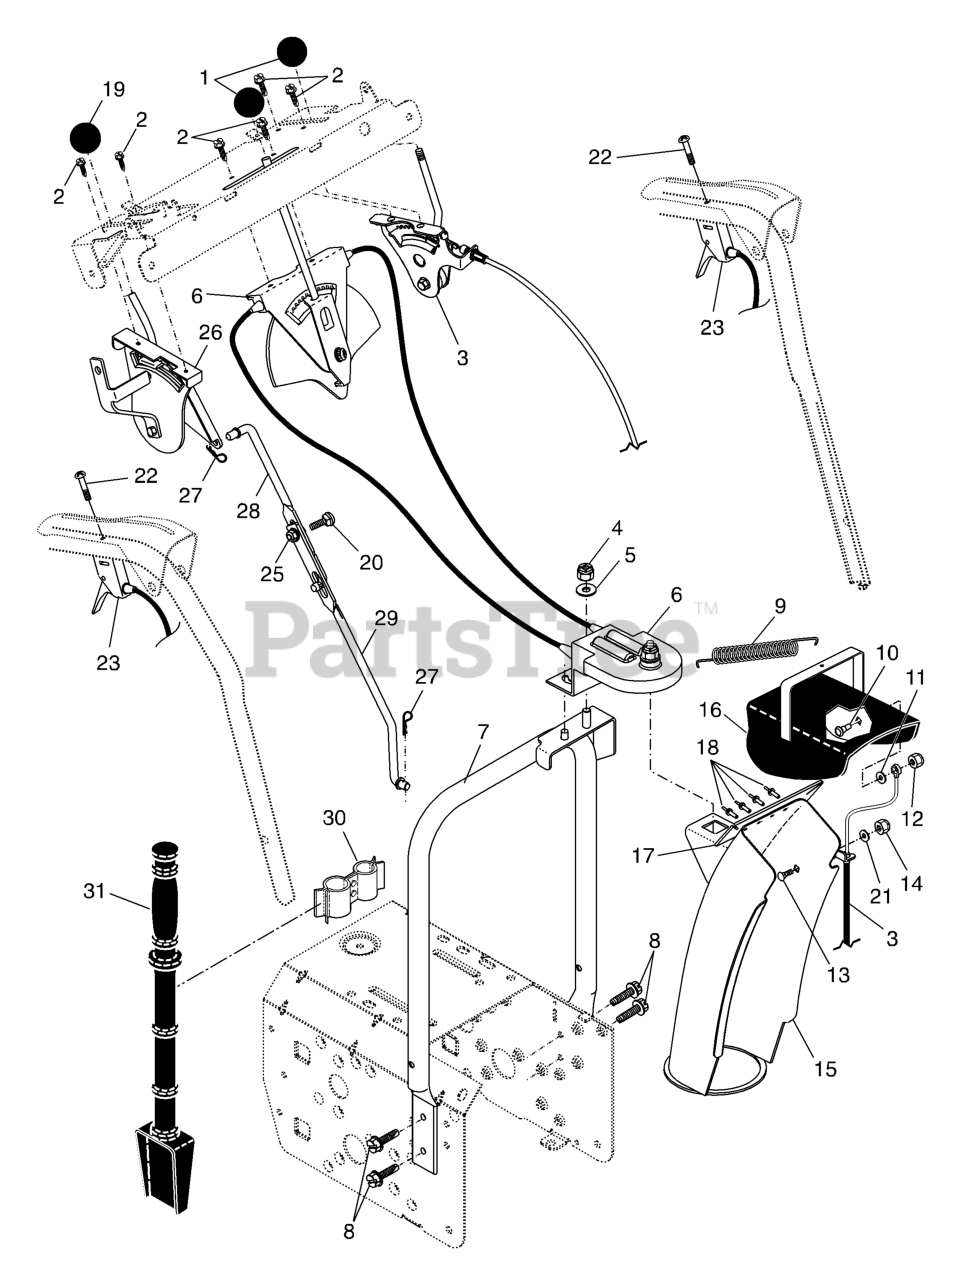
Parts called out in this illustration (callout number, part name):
1	KNOB, LEVER
2	SCREW #10-24 X 5/8
3	CONTROL.CABLE.DEFLECTOR
4	NUT
5	WASHER
6	CONTROL.CABLE.CHUTE.RO
7	SUPPORT CHUTE ROTATER
8	SELF-TAPPING SCREW 5/16-18X3/4
9	SPRING.DEFLECTOR.REM.CHUTE
10	BOLT, SHOULDER
11	WASHER, NYLON FRICTION
12	LOCKNUT.NYLOC.1/4-20
13	BOLT
14	NUT.71038.31-18.HEX.NYLOCK
15	CHUTE ASSY
16	DEFLECTOR.WELDMENT.PNT.ORANGE
17	SEAL, DEFLECTOR
18	RIVET BLIND
19	RP KNOB, SPEED CONTROL LEVER
20	BOLT
21	WASHER.20X8.5
23	STEERING.CONTROL.SNOW.BLUE
25	NUT.FLANGE.5/16
26	HEAD ASSY SPEED
27	SPRING RETAINER
28	ROD, UPPER SPEED CONTROL
29	ROD, LOWER SPEED CONTROL.SNOW
30	CLAMP.ASM.CLEANOUT.TOOL.SNOW
31	CLEAN OUT TOOL
